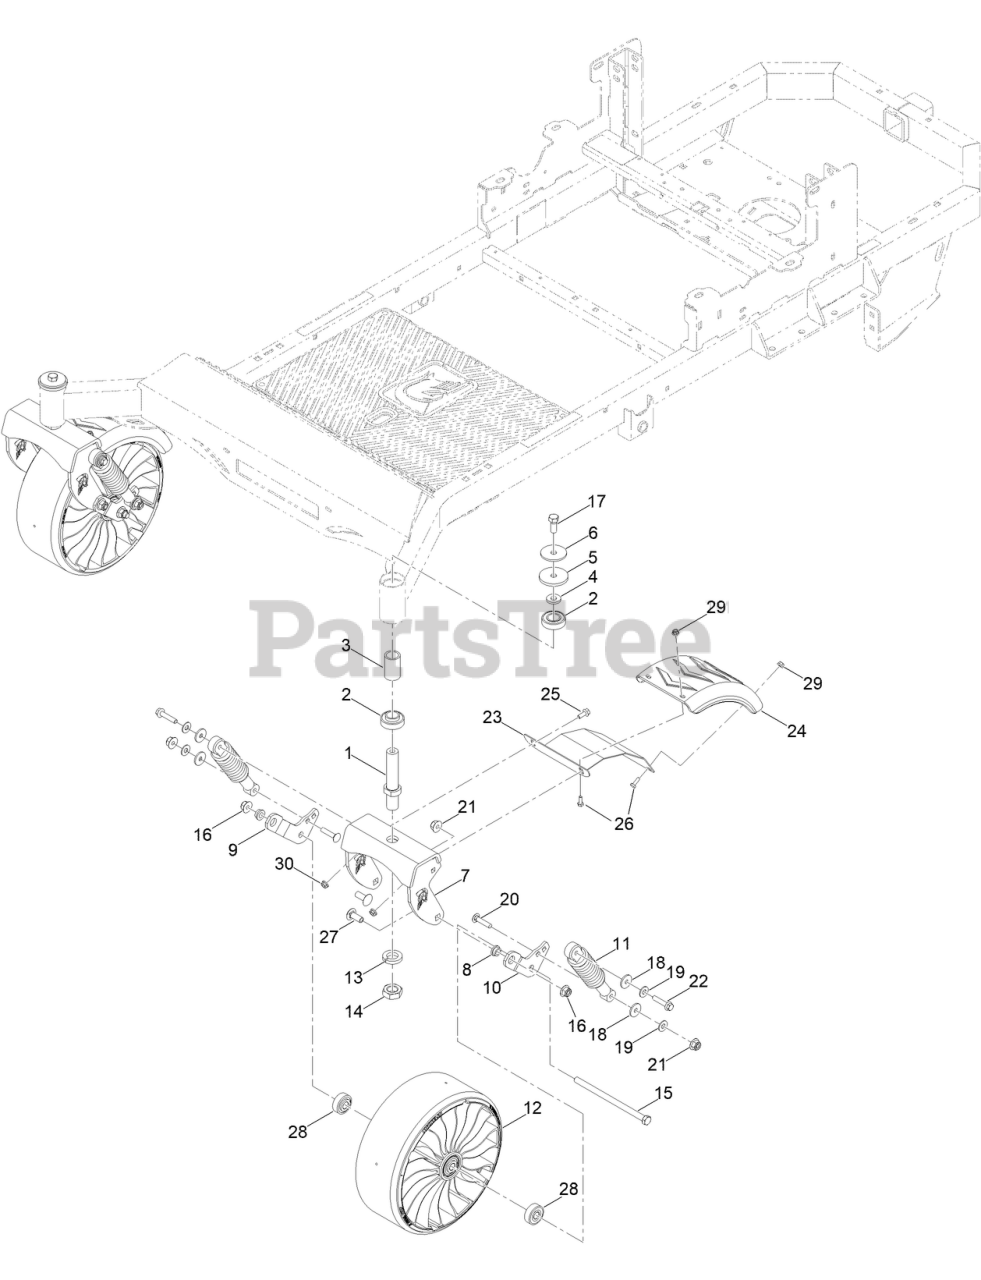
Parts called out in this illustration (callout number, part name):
1	MWR CASTER SHAFT
2	BEARING-BALL
3	CASTER FORK SHAFT BEARING SPACER
4	1/2 FENDER WASHER 1-1/4IN OD ZINC
5	FT HUB PLASTIC WASHER
6	MWR CASTER SHAFT WASHER BLACK
7	2022 FT FORK SHOCK ASSY BLACK
8	1/2IN ID X 3/4IN OD X 3/8IN FLANGE BUSH
9	2022 SRT TWEELS SUSP BRKT RT BLACK
10	2022 SRT TWEELS SUSP BRKT LT BLACK
11	2020 RZ PRO SEAT / FT FORK SHOCK
12	FRT TWEEL SMOOTH CASTER 13X6.5N6 (36271)
13	1IN L/W MED SPLIT ZC
15	1/2-13 X 8-1/2 HEX C/S GR 5 ZINC YELLOW
16	NUT-LOCK
17	1/2-20 X 1-1/4 HEX FLANGE BOLT GR 8 YZ
18	FLT WASHER 1.25ODX.38IDX.125 THK PLA
19	WASHER-FLAT
20	3/8IN-16X1-3/4IN G8 CARRIAGE BOLT
21	3/8-16 NYLON INSERT FLANGE L/NUT YZ
22	3/8-16 X 1-.75 HEX FLG BOLT GR 8 YELLOW
23	2020 SPARTAN FT FENDER BRKT BLACK
24	SPARTAN FORK FT FENDER
25	SCREW-HHF
26	SCREW-HH
27	1/2-13 X 1.25 CARRIAGE BOLT YELLOW
28	BUSHING SET FOR FT TWEEL 38182
30	NUT-HF
